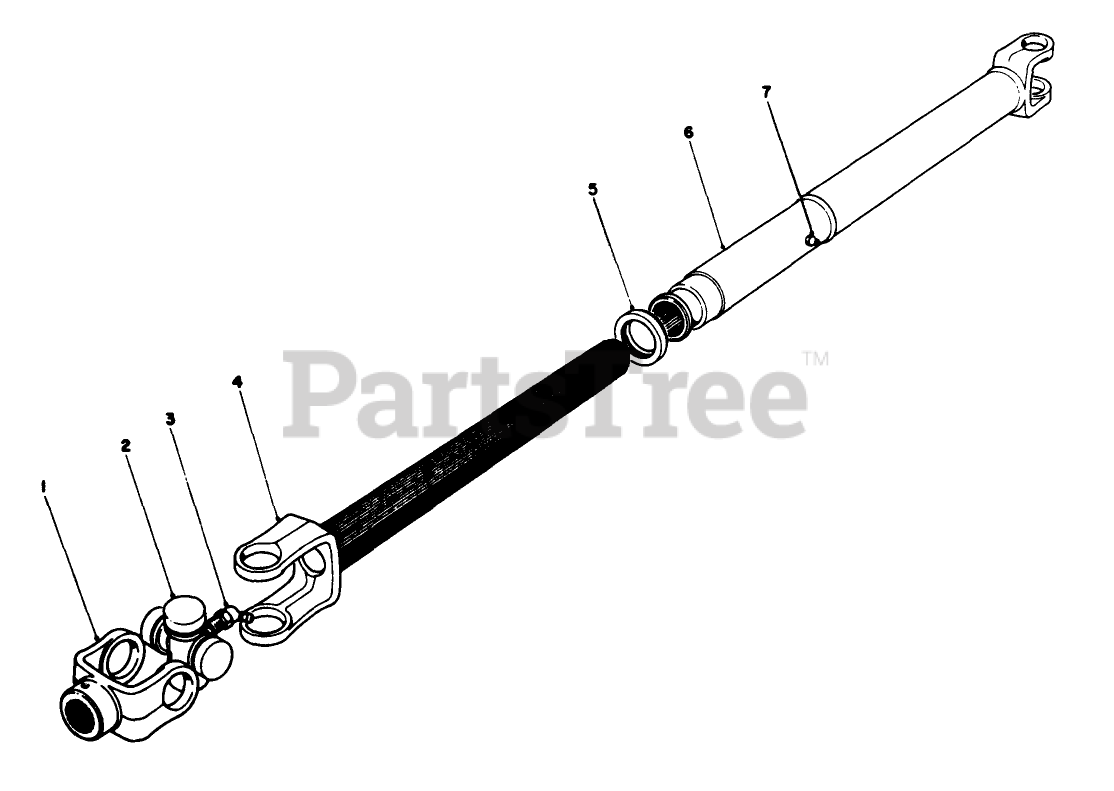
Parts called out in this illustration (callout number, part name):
1	End Yoke
1	YOKE-END
2	U Joint Kit
2	U-JOINT KIT
3	Grease Fitting
3	FITTING-GREASE
4	Slip Yoke Shaft
4	Shaft-Slip Yoke
5	DUST CAP ASM
6	Slip Yoke Tube
7	LUBE FITTING (21-3090
7	Fitting-Grease
